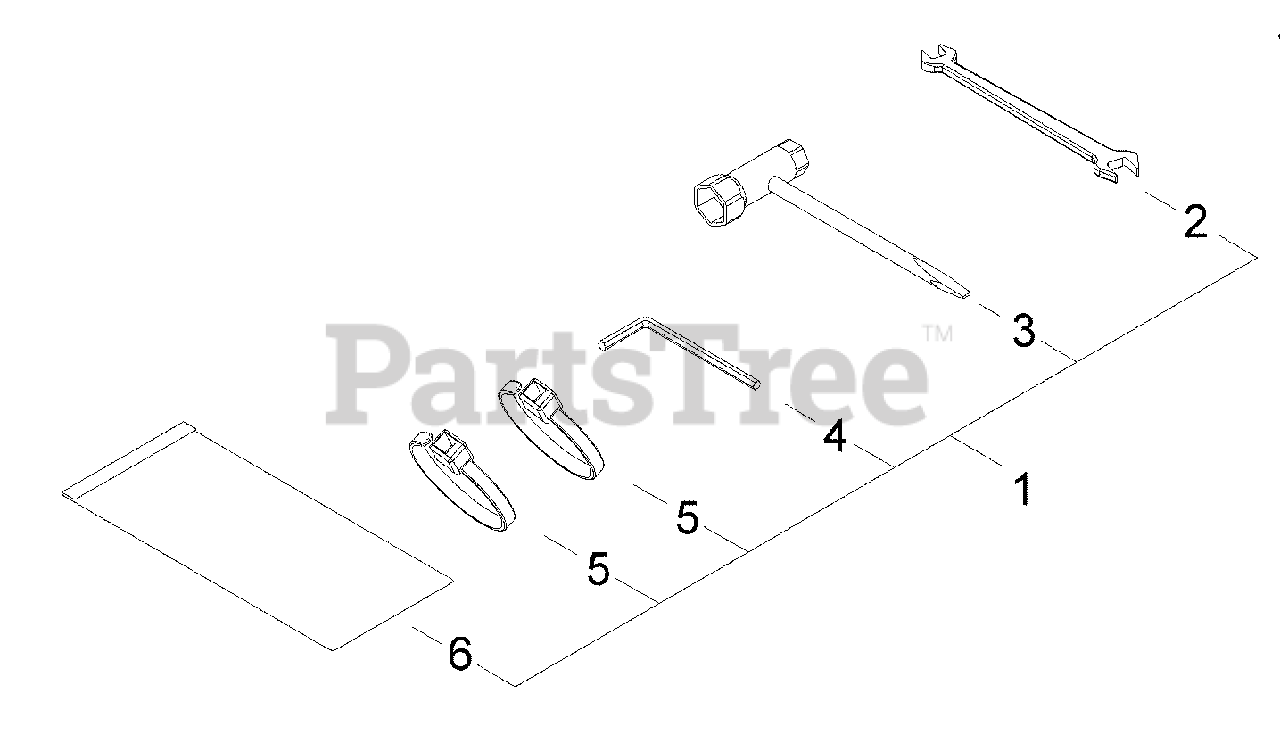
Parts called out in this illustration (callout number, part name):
1	TOOL KIT, SERVICE
2	SPANNER 8×10
3	T-WRENCH 16×13
4	WRENCH, ALLEN 4 MM
5	TIE, CABLE
6	BAG, TOOL
